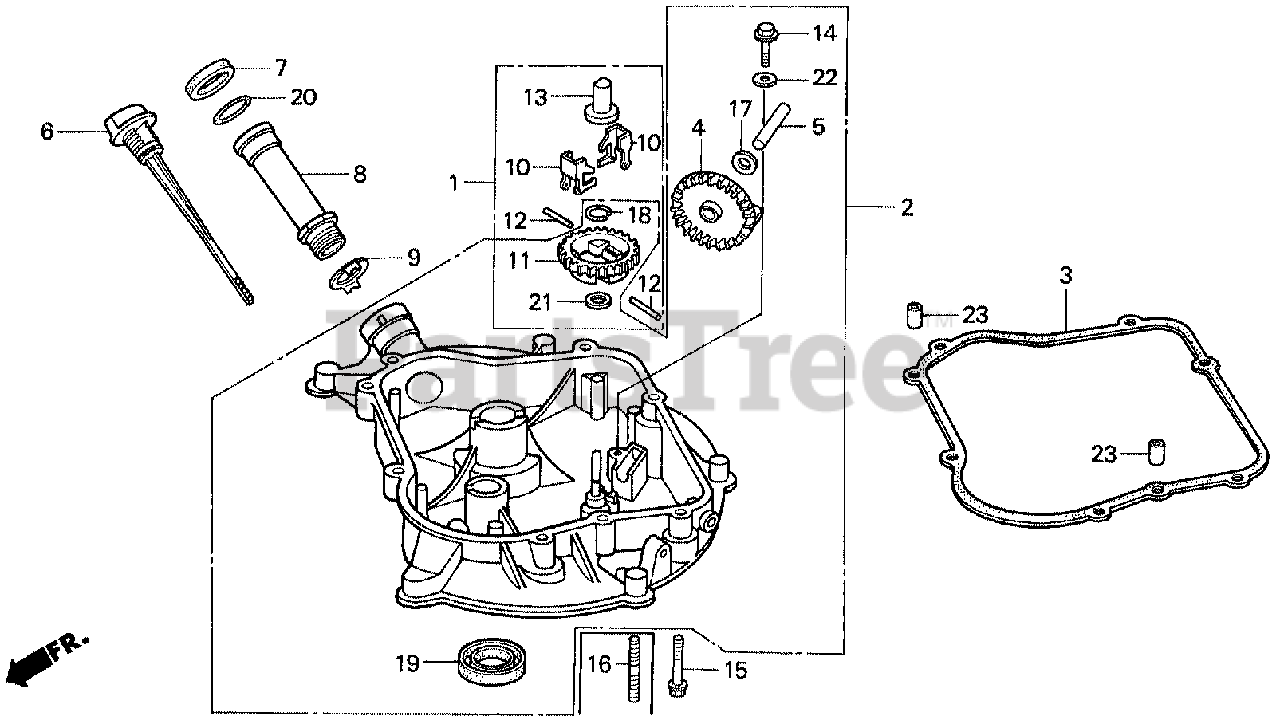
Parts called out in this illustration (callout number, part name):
1	GOVERNOR KIT (STD)
2	PAN ASSY., OIL
3	GASKET, CASE COVER
4	SLINGER, OIL
5	SHAFT, OIL SLINGER
6	CAP, OIL FILLER
7	GASKET, OIL FILLER CAP
8	EXTENSION, OIL FILLER
9	WASHER, EXTENSION LOCK
10	WEIGHT, GOVERNOR
11	HOLDER, GOVERNOR WEIGHT
12	PIN, GOVERNOR WEIGHT
13	SLIDER, GOVERNOR
14	BOLT, FLANGE (5X16)
15	BOLT, FLANGE (6X28) (CT200)
16	BOLT, STUD (6X25)
17	WASHER (6MM)
18	CLIP, GOVERNOR HOLDER
19	OIL SEAL (20X34X6)
20	O-RING (22.1X2.2)
21	WASHER, PLAIN (6MM)
22	WASHER, PLAIN (5MM)
23	PIN, DOWEL (8X14)
